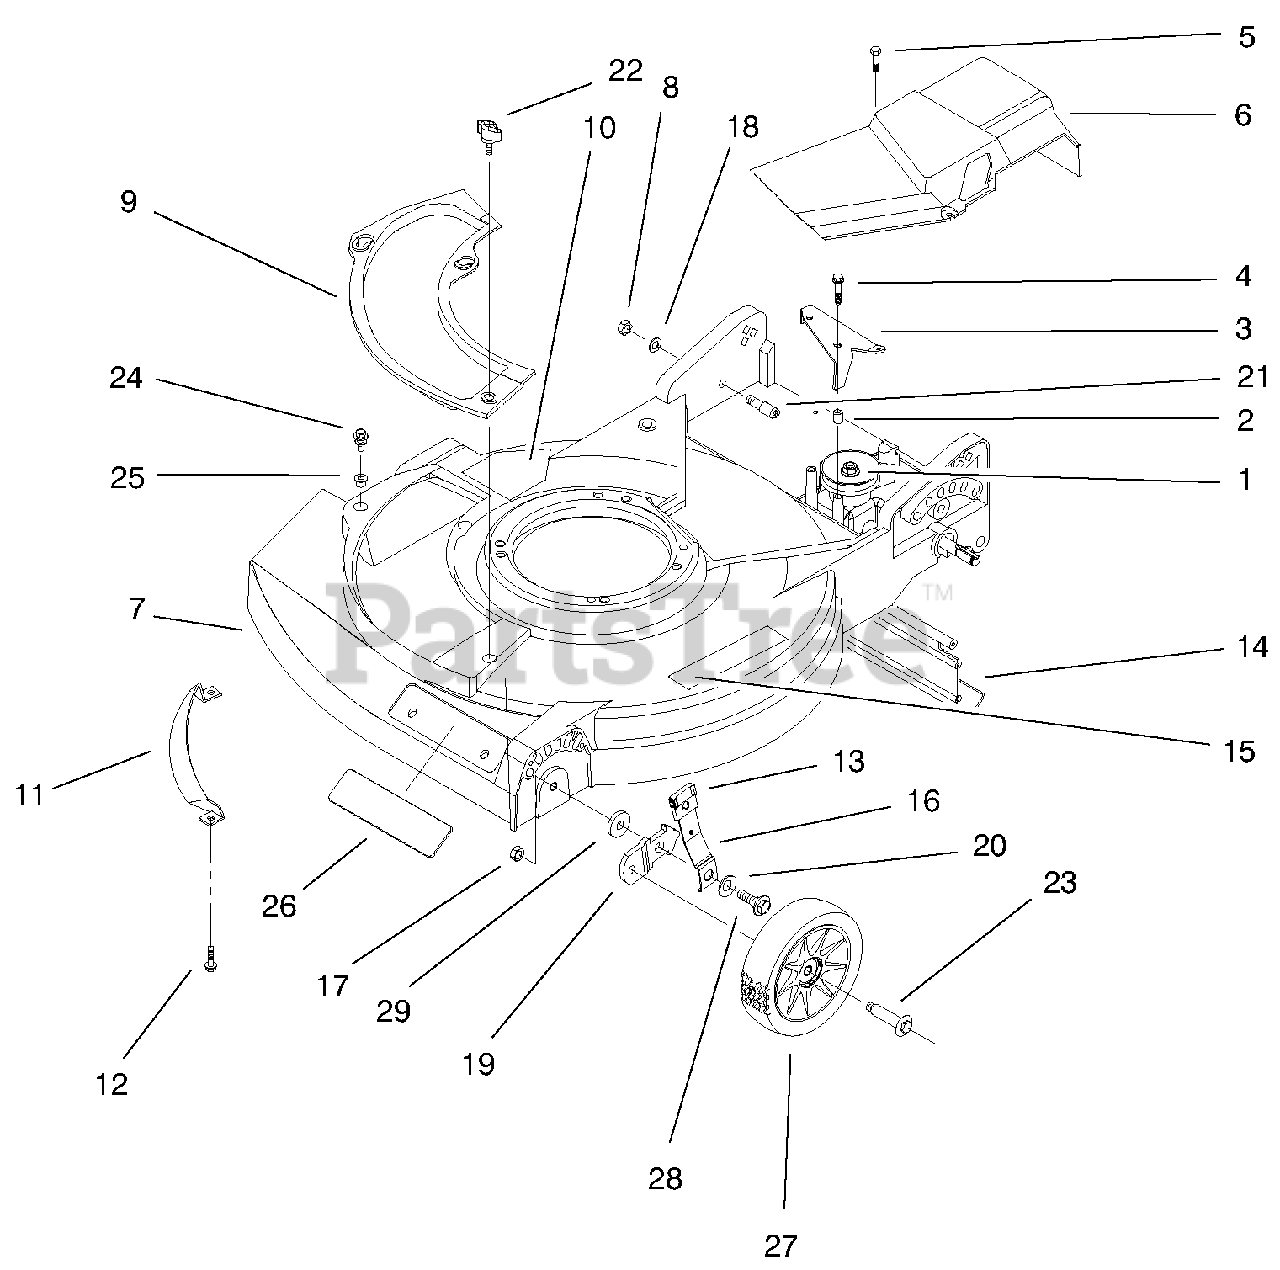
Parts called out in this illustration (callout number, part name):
1	ASM-Gear Case
2	Bushing-Spacer
3	Bracket-Actuator
4	Screw
5	Screw-Thread Forming
6	Cover-Drive
7	Housing-21" Sp
8	Nut-Lock
9	Plate-Cover
10	Decal-Danger
11	Toe Bar 21
12	Screw-HWH
13	Knob-Height Adjust
14	Shield-Trailing
15	Decal-Warning
16	ASM-Spring Arm
17	Nut-Lock
19	Bracket-Wheel Height Adj
20	Washer-Spring
21	Bolt-Shoulder
22	Knob-Cover Plate
23	Bolt-Wheel
24	Screw-Sems
25	Grommet-Plastic
26	Decal-Deck
27	Wheel & Tire
28	Bolt-Shoulder
